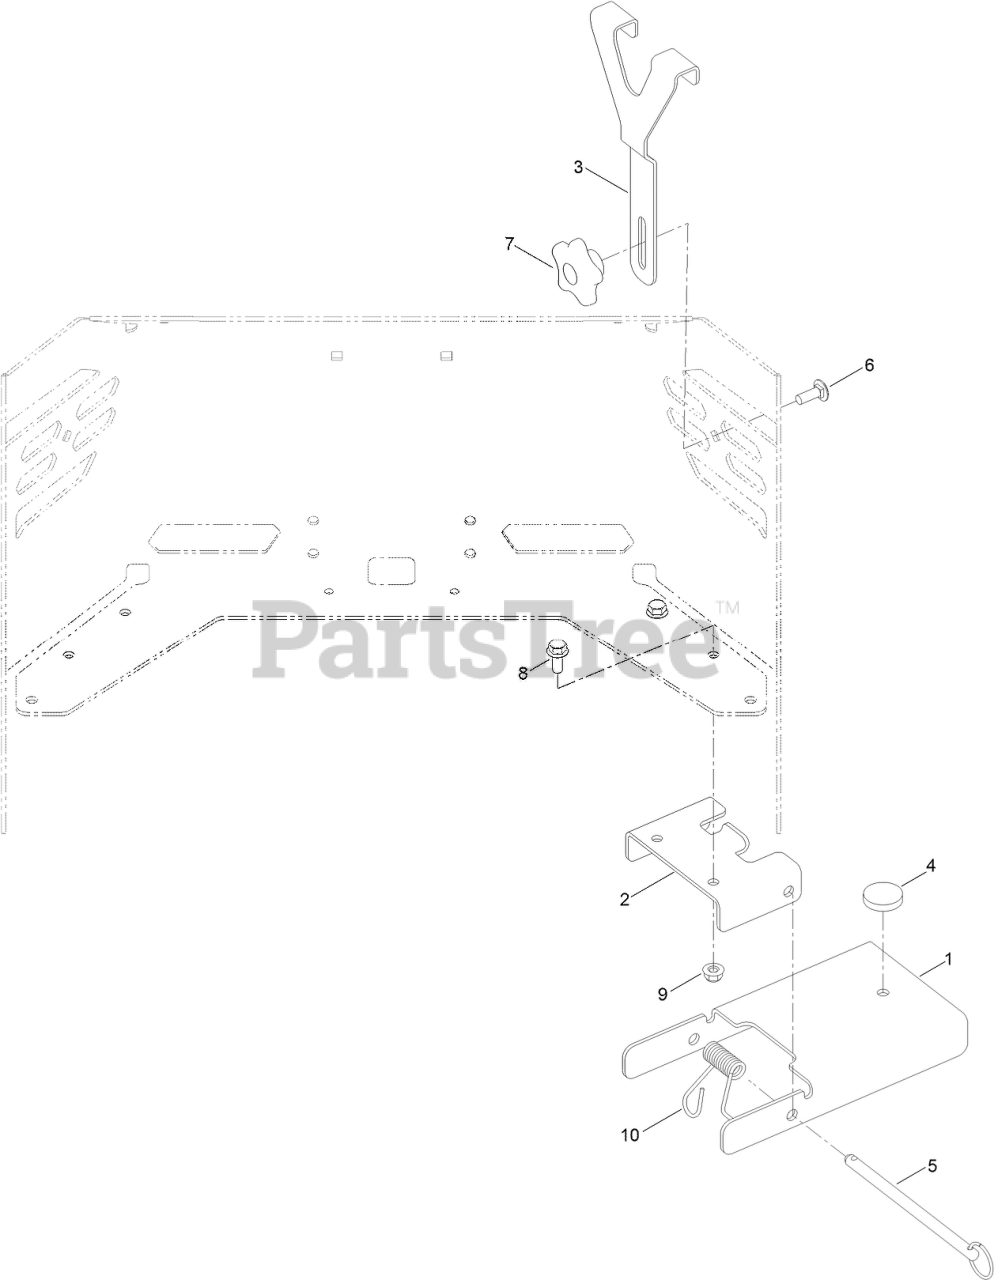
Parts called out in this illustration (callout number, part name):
1	BRACKET-SUPPORT, BUCKET
2	BRACKET-BUCKET
3	BRACKET-BUCKET
4	BUMPER-PUSH-IN, RUBBER
5	PIN-LOCKING
6	BOLT-CARR
7	KNOB-HANDLE
8	SCREW-HHF
9	NUT-HF, NI
10	SPRING-TORSION
